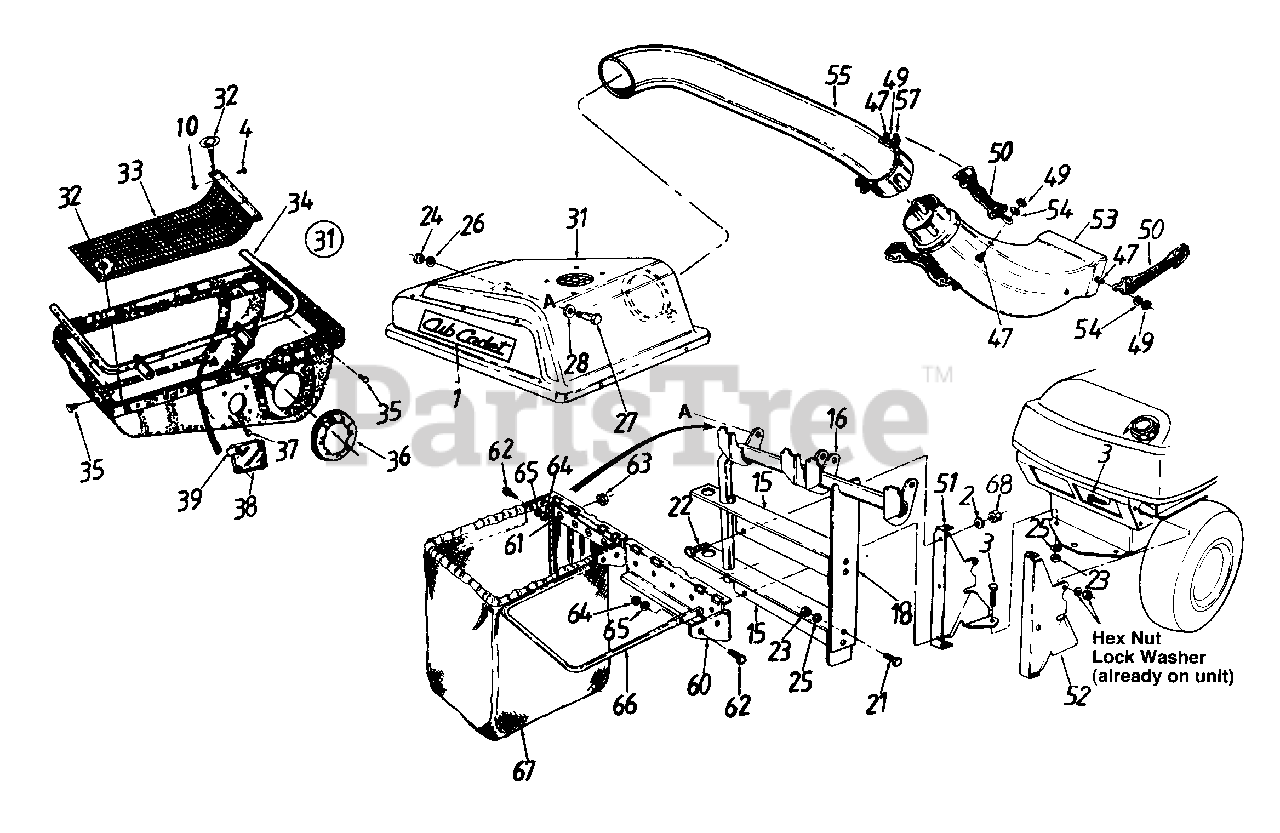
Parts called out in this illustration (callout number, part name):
1	Cub Cadet Name Plate
2	Fl-Wash. 1/4" I.D.
3	Hex Bolt 5/16-18 x 1.0" Lg.
4	Pop Rivet .188 Dia.
10	Flat Wash. 1/4" I.D.
21	Hex Bolt 5/16-18 x .75"
22	Hex Bolt 1/4-20 x .62" Lg.- Grade 5
23	Hex Nut 5/16-18 Thd.
24	Hex Nut 3/8-16 Thd.
25	L-Wash. 5/16" I.D.
26	L-Wash. 3/8" I.D.
27	Shld. Bolt 3/8-16 x .50" Dia.
28	Bell-Wash. .505" I.D. x 1.0" O.D.
31	Grass Catcher Cover Ass'y.
32	Twist Fastener
35	Hex AB-Tap Scr. 1/4 x .62"
36	Seal - 7"
37	Truss B-Tap Scr. #10 x .5" Lg.
38	Plastic Plate
39	Speed Nut
47	Hex Bolt 1/4-20 x .625"
49	Hex Ins. L-Nut 1/4-20 Thd.
50	Retainer Strap Ass'y.
51	Catcher Support Brkt. - L.H.
52	Catcher Support Brkt. - R.H.
53	Discharge Chute
54	L-Wash. .27" I.D.
55	Catcher Tube
57	Retainer Hook Brkt.
61	Truss Mach. Scr. #10-24 x .5"
62	Hex Bolt 1/4-28 x .88"
63	Hex Sems Nut #10-24 Thd.
64	Hex Nut 1/4-28 Thd
65	L-Wash. 1/4" I.D.
67	Grass Catcher Bag
68	Hex L-Nut 1/4-20 Thd.
